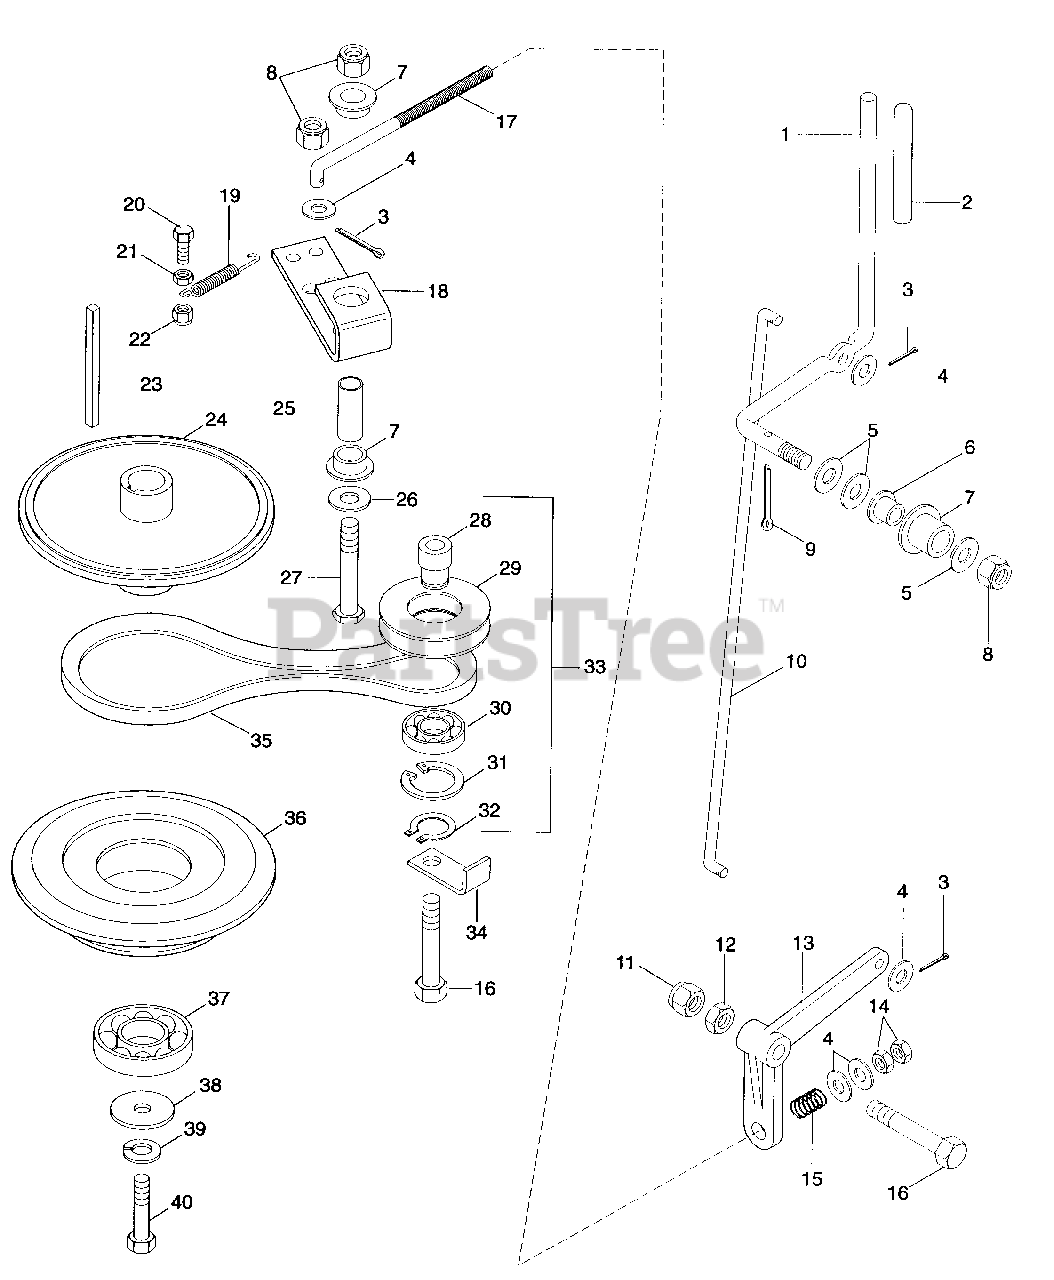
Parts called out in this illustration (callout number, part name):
1	Lever, PTO Actuating
2	Grip, PTO Lever
3	Pin-Cotter .09 x .75
4	Washer-Flat-Steel .406 x .812 x .065
5	Washer-Flat-Steel .531 x 1.250 x 1.00
6	Bushing-Flange .515 x .750 x .745 x 1.00
7	Bushing-Flange .762 x 1.0 x .580 x 1.48
8	Nut-Locking-Nylon .50-13 Grade 5
9	Pin-Cotter .188 x 1.25
10	Rod, PTO Control
11	Nut-Locking .50-13
12	Nut-Jam .50-13 Grade 2
13	Lever, PTO Clutch
14	Nut-Hex .375-16 Grade 2
15	Spring-Compression.125 x.78 x 1.00
16	Bolt-Hex .50-13 x 2.50 Grade 5
17	Rod, PTO Clutch Actuating
18	Arm, Idler Pivot
19	Spring-Tens .061 x .50 x 3.5
20	Bolt-Hex .31-18 x 1.00 Grade 5
21	Nut-Hex .312-18 Grade 2
22	Nut-Locking-Nylon .312-18 Grade 2
23	Key-Square .250 x 3.60 x.250
24	Hub, PTO Clutch
25	Bushing, Steel .560 x .745 x 2.04
26	Washer-Flat-Steel .531 x 1.062 x .095
27	Bolt-Hex 1/2-13 x 2.75
28	Bushing, Flange .515 x .787 x 1.41
29	Sheave, Idler
30	Bearing-Ball 1.85 x .787 x .55
31	Ring-Retaining-Internal 2.054 x .062
32	Ring-Retaining Truarc
33	Assembly, Idler Sheave
34	Guard, Belt
35	V-Belt A-RMA 13.8 x .480
36	Sheave, Mower Clutch
37	Bearing, Ball, 1.57 x 3.15 x .71
38	Washer-Special .469 x 2.000 x .250
39	Washer-Lock .44 Reg
40	Bolt-Hex .44-20 x 2.50
